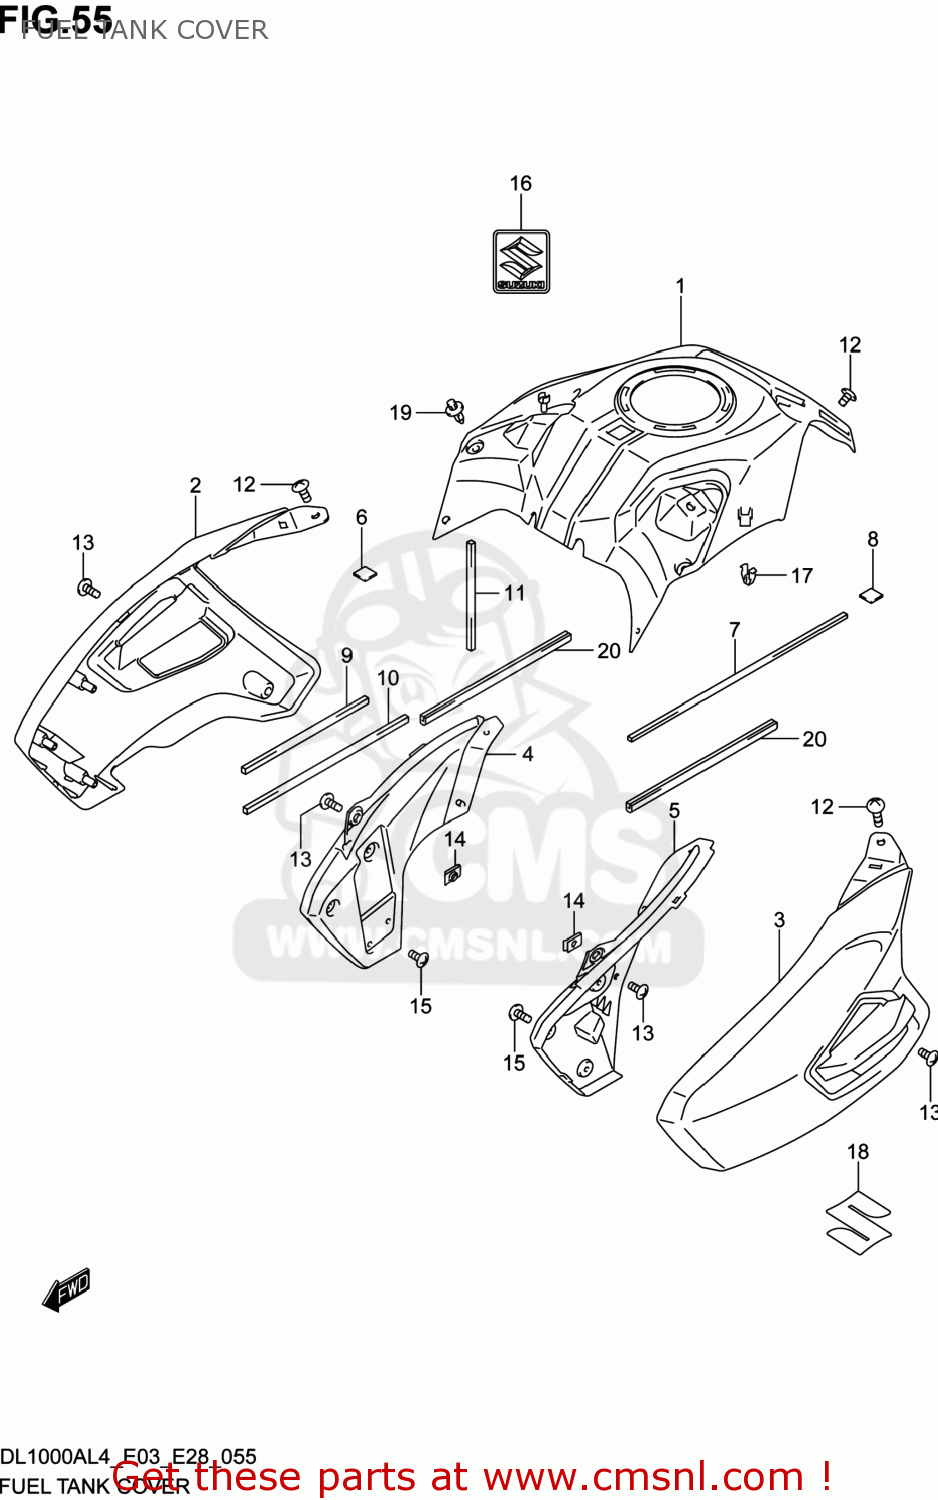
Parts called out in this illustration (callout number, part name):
1	COVER,FUEL TANK CENTER
2	COVER,FUEL TANK SIDE,R
3	COVER,FUEL TANK SIDE,L
4	COVER,FUEL TANK FRONT,R
5	COVER,FUEL TANK FRONT,L
6	CUSHION,METER COVER RE
7	CUSHION,FUEL TANK COVER
8	CUSHION,WINDSCREEN COVER
9	CUSHION,TANK COVER SIDE NO.1
10	CUSHION,TANK COVER SIDE NO.2
11	CUSHION,TANK COVER SIDE NO.3
12	BOLT(6X8)
13	BOLT(5X13)
14	NUT
15	SCREW
16	EMBLEM,"S"
17	CLIP
18	EMBLEM, S
19	CLIP(BLACK)
20	MOLDING,FUEL TANK RR
